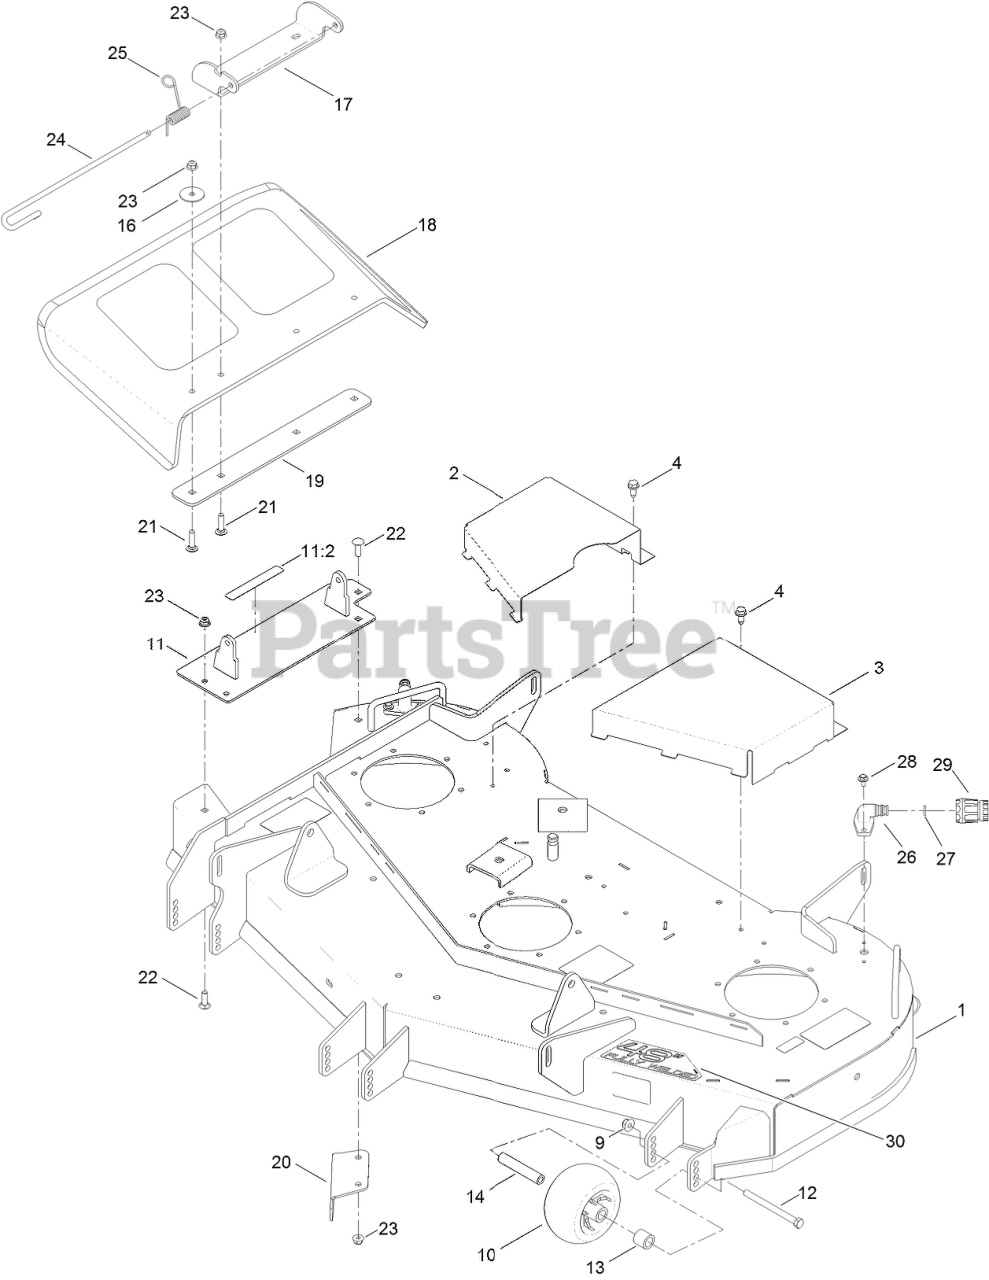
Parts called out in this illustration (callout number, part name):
1	DECK-48 INCH (W/DECALS)
2	COVER-BELT
3	COVER-BELT
4	SCREW-HWHTF
9	NUT-HF, NI
10	ROLLER-SCALP, ANTI
11	PIVOT-DEFLECTOR
11:2	DECAL-DANGER
12	SCREW-HH
13	SPACER-AXLE, REAR
14	TUBE-SPANNER
16	WASHER-FLAT
17	BRACKET-DEFLECTOR, UPPER
18	DEFLECTOR
19	PLATE-DEFLECTOR
20	BAFFLE-CUTOFF
21	SCREW-CARR
22	SCREW-CARR
23	NUT-HF, NI
24	PIN-CHUTE
25	SPRING-TORSION
26	FITTING-WASHOUT
27	O-RING
28	SCREW-HHFTF
29	CONNECTOR-HOSE
30	DECAL-DECK
